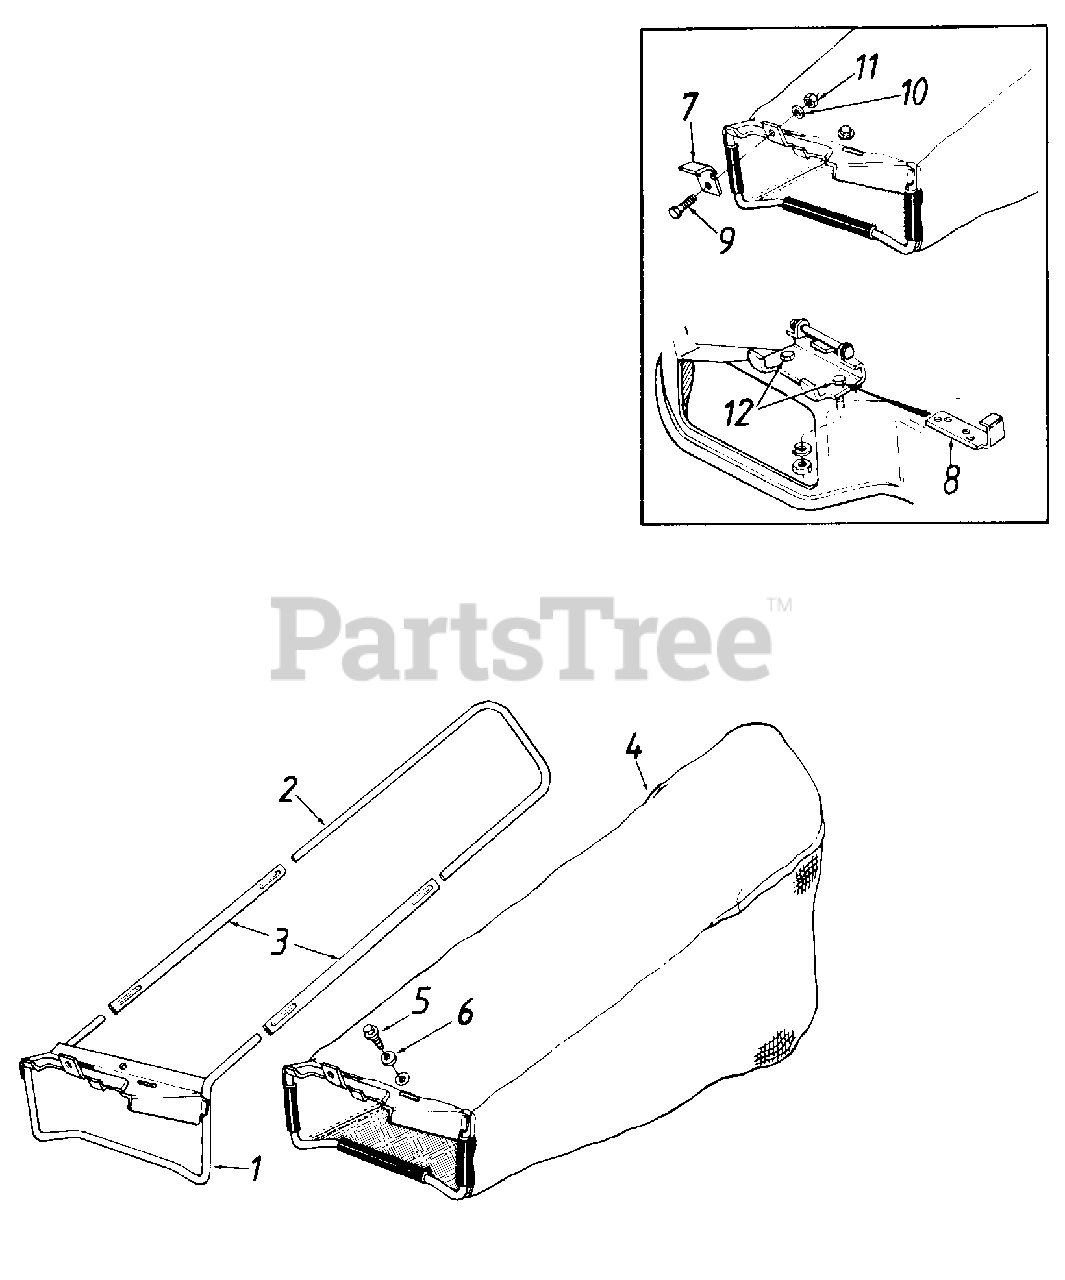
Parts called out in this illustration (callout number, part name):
1	Frame-Lower Ass'y.
4	Grass Bag
5	Hex Wash Hd. TT-Tap Scr. 1/4-20 x 5" Lg.
6	Bell-Wash. 1/4" I.D.
7	Deflector Stop
8	Support Plate
9	Hex Bolt 1/4-20 x .5" Lg.
10	L-Wash. 1/4" I.D.
11	Hex Nut 1/4-20 Thd.
12	Hex Bolt 1/4-20 x .62" Lg.
